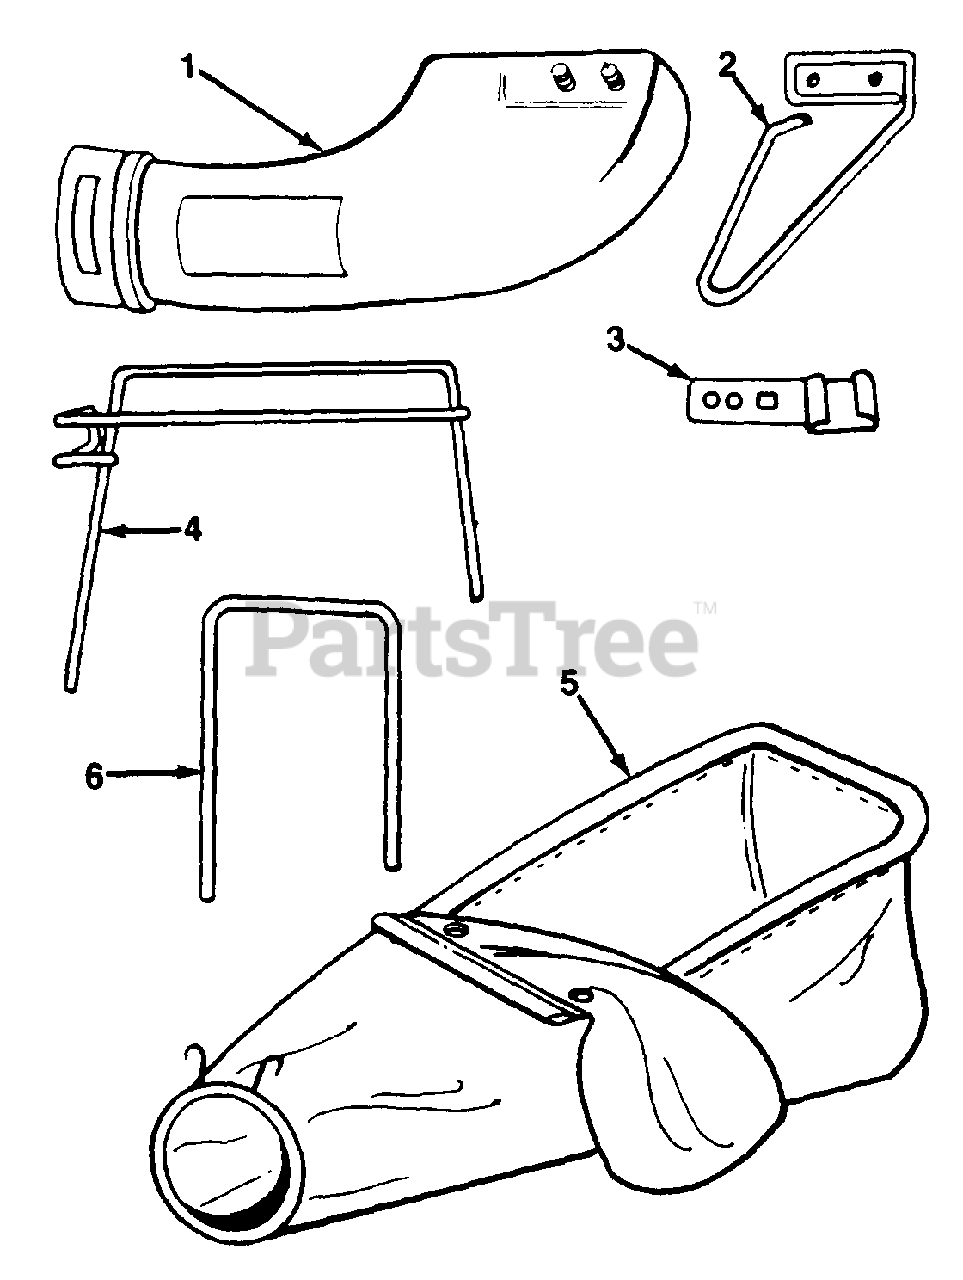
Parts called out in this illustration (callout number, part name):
1	Plastic Chute
2	Chute Mounting Bracket w/Wire
3	Handle Bracket
4	Bag Frame
5	Bag w/Clamp Ring
6	Upper Support Tube
